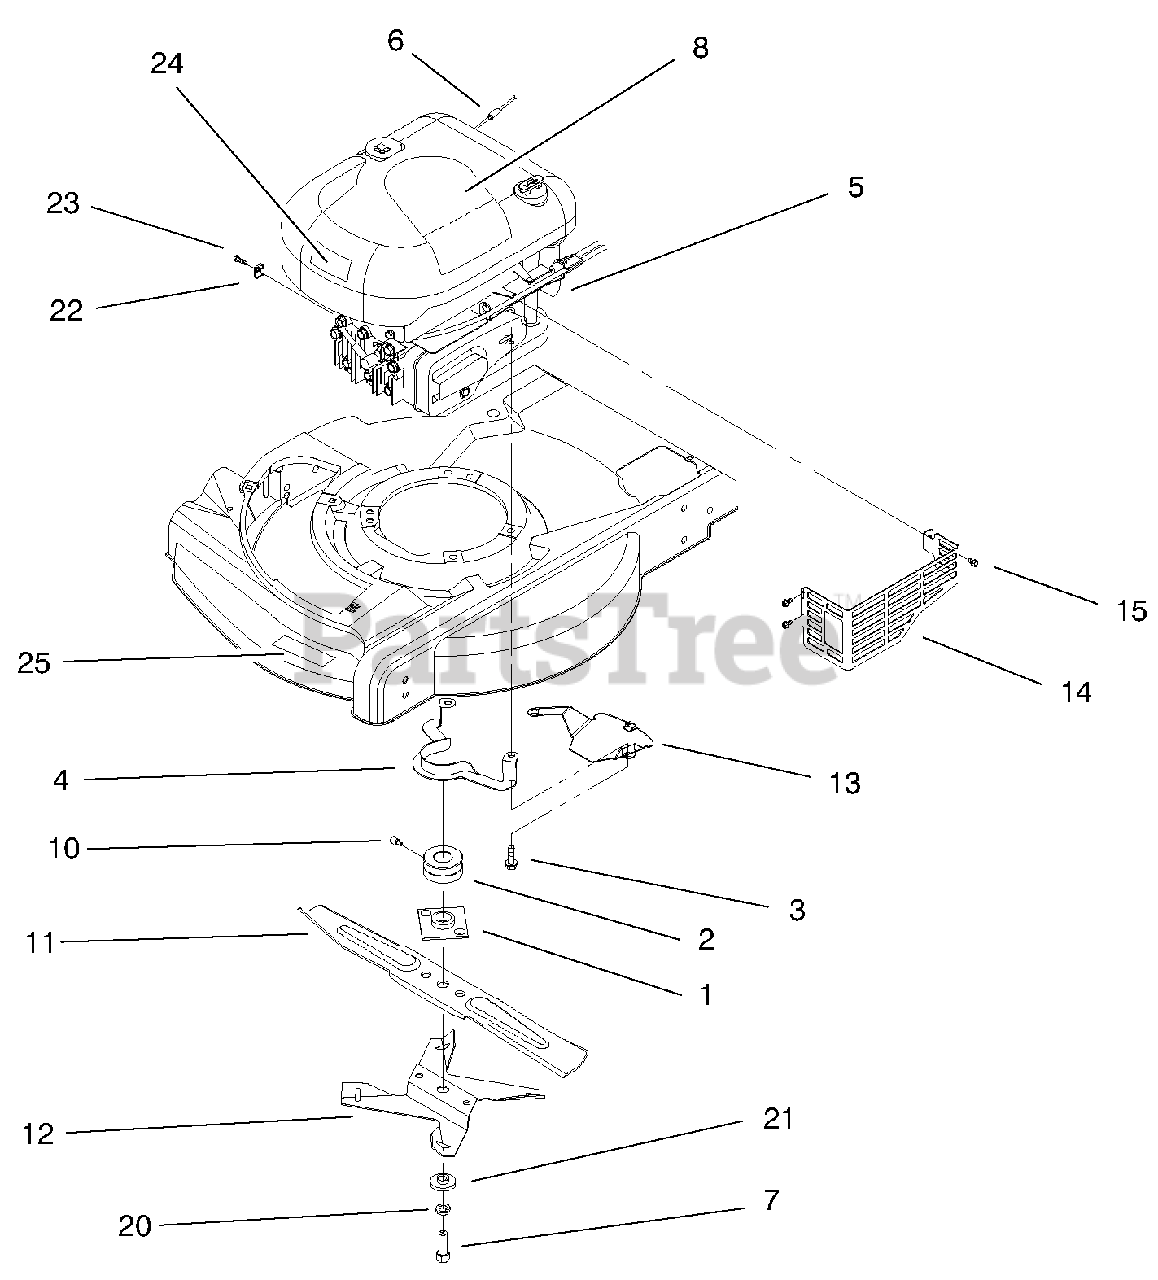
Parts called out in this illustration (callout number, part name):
1	ASM-Plate & Collar
2	Pulley-Engine
3	Screw-Engine Mount
4	Guide-Belt
5	ASM-Engine
6	Rope-Stop
7	Bolt-Blade
8	Decal-Recoil
10	Screw-Set
11	Blade-21" Whirl
12	Fan-Mulching
13	Shield-Grass
14	Shield-Muffler
15	Screw-HWHTF
20	Washer-Lock
21	Spacer-Blade
22	Clamp-Casing
23	Screw-Clamp
24	Applique-Shroud
25	Decal-Deck
